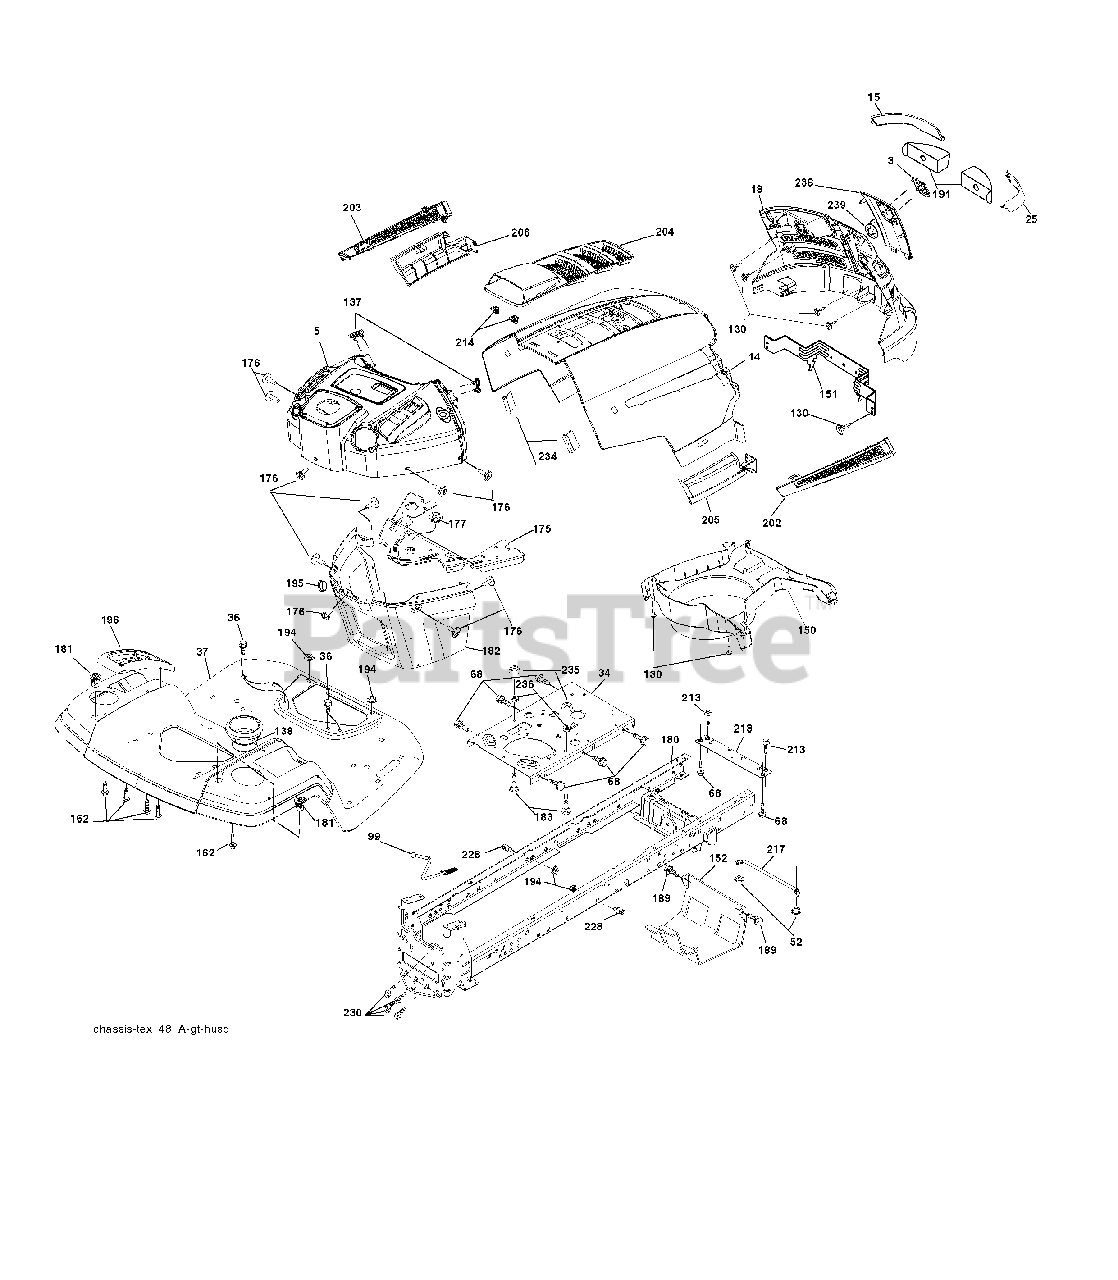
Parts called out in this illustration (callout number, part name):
3	Logo
5	Dash
14	Hood
15	Lens LH
18	Grille/Lens Asm.
25	Lens RH
34	Plate Engine
36	Screw 5/16-18 x 3/4
37	Fender
52	Nut Crown Lock 5/16
68	Screw THDROL 5/16-18 x 1/2
99	Rod Asm Bypass
130	Screw
137	Bumper Dash
138	Cupholder
151	Bracket Pivot
152	Shield Browning
175	Crossmember
176	Screw 10-24 x 5/8
177	Bushing Steering
180	Chassis
181	Bushing Mtg. Fender Crgo
182	Dash Lower
183	Bolt 5/16-18 unc x 1-1/4
189	Screw 5/16-18 x 3/4
191	Insert Reflective
194	Nut Lock Hex Flange 5/16-18
195	Plug Dash
196	Console Asm. Deck Lift
202	Vent Side Hood RH
203	Vent Side Hood LH
204	Vent Top Hood
205	Skirt Side RH
206	Skirt Side LH
213	Bolt 5/16-18 x 3/4
214	Clip Retainer
217	Rod Pivot Hood
218	X-Piece Hood Stop
228	Stud Fastener
230	Bolt Shoulder 5/16-18
234	Bumper Hood
235	Spacer Fender
236	Nut Lock 5/16-18 unc
238	Trim
239	Clip Tinnerman
